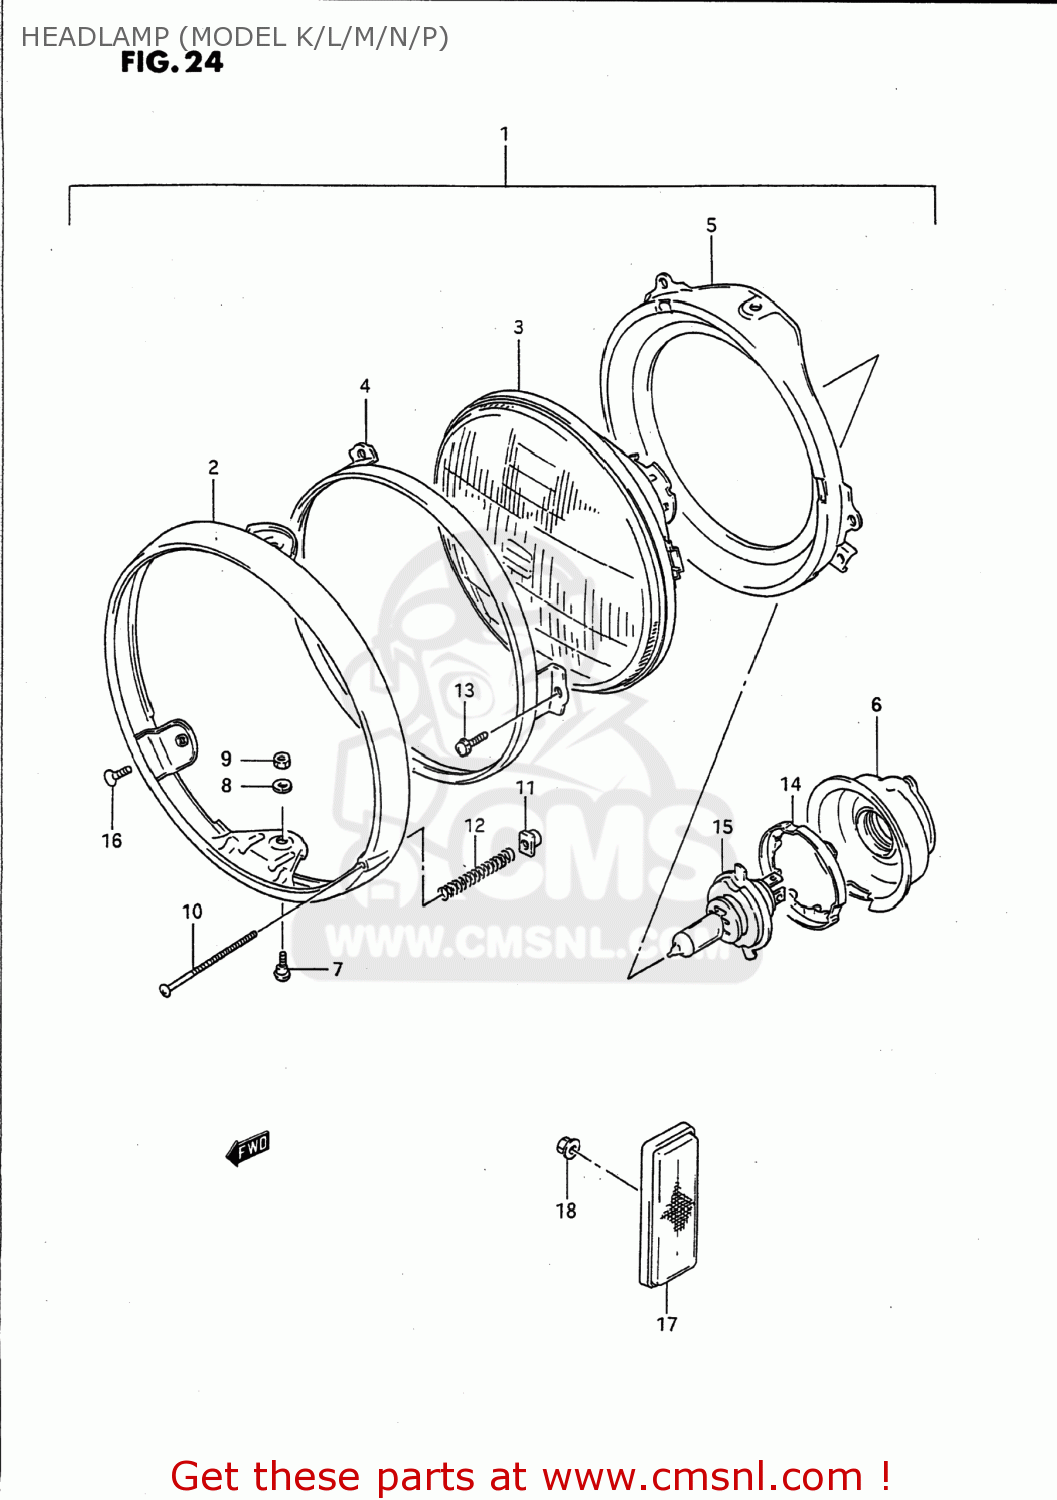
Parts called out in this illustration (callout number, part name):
1	HEADLAMP ASSY
2	RIM,HEADLAMP
3	LAMP UNIT
4	RETAINING RING
5	RING
6	COVER,HEADLAMP SOCKET
7	H/LAMP LENS UNIT FITING SCRE
8	LOCK WASHER
9	NUT
10	SCREW,HEADLAMP ADJUST
11	NUT
12	SPRING,ADJUSTING
13	SCREWM4X0.7X10
14	SETTING,BULB
15	BULB(12V60/55W,H4)
16	SCREW 5X12
17	REFLEX REFLECTOR,FR SIDE
18	NUT
